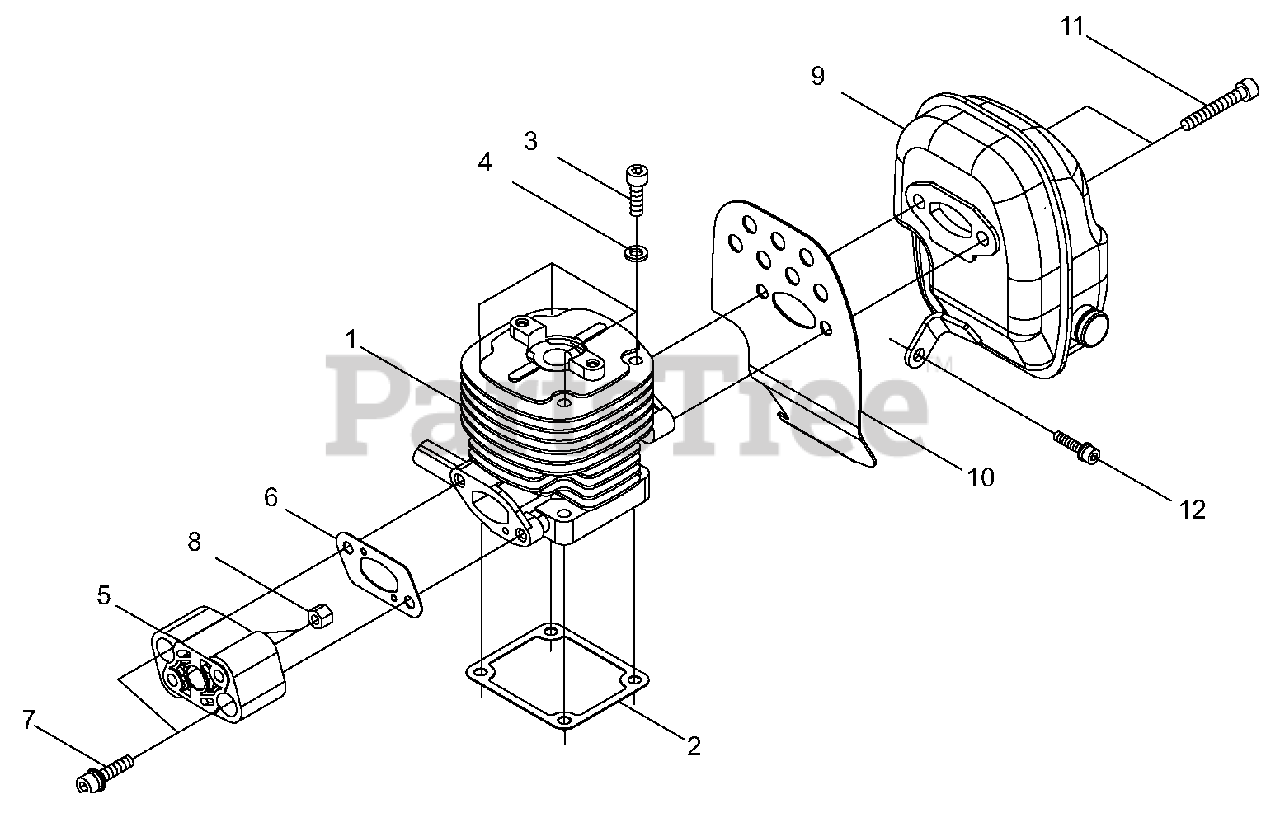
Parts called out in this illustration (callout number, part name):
1	CYLINDER
2	GASKET, CYLINDER
3	BOLT 5×25
4	WASHER, SPRING 5
5	INSULATOR
6	GASKET, INTAKE
7	BOLT M5×25
8	NUT M5×6.3
9	MUFFLER
10	HEAT SHIELD, EXHAUST
11	BOLT 6×25
12	BOLT M5×12
